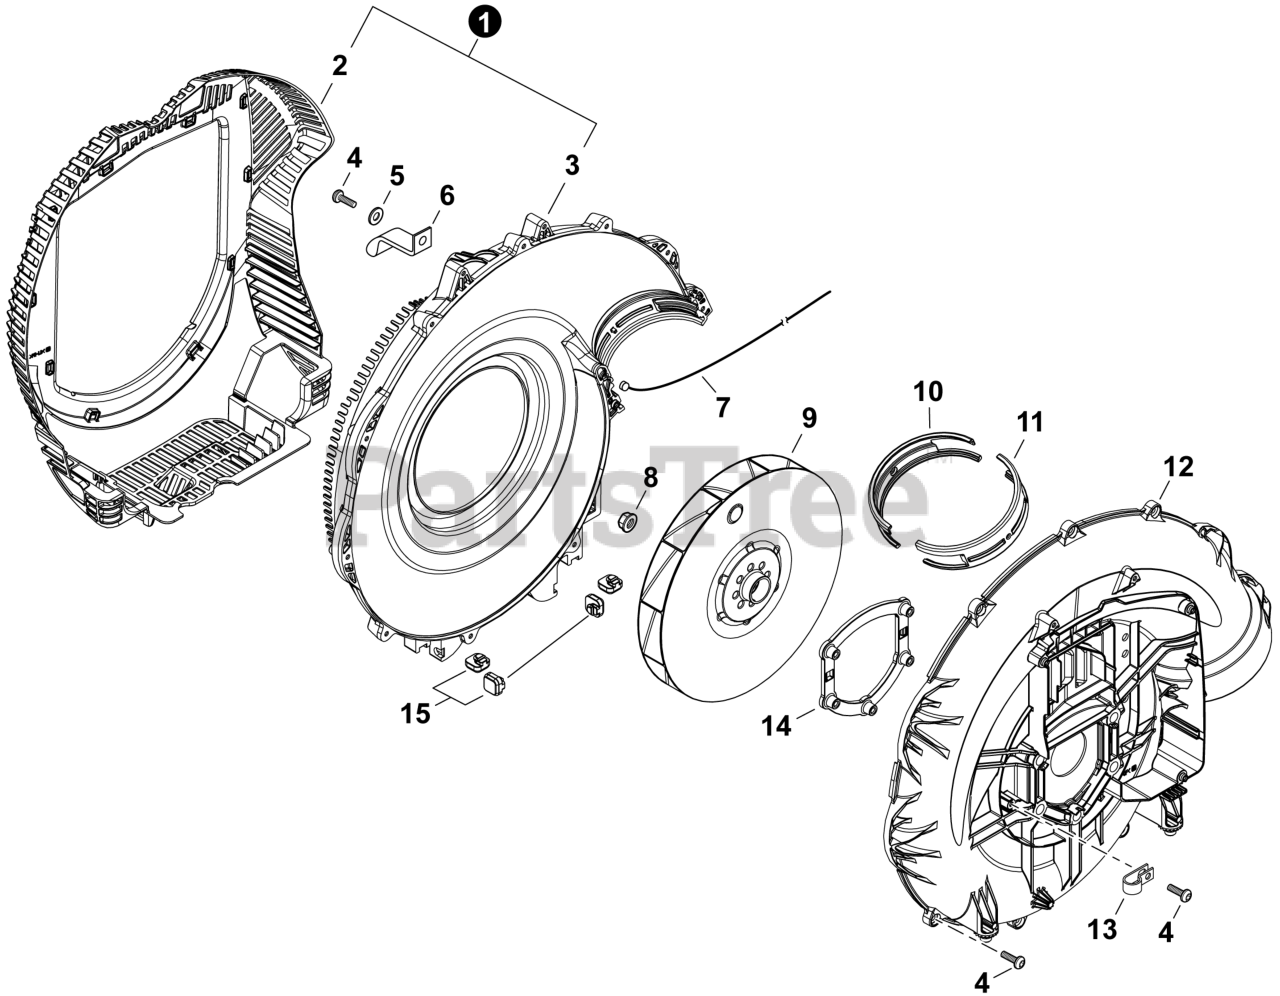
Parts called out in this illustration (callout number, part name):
1	FAN COVER/GUARD SET
2	GUARD, DEBRIS
3	COVER, FAN
4	BOLT, TORX 5x20
5	WASHER 5.5x16x0.8
6	STRAP, SAFETY
7	WIRE, ANTI-STATIC
8	NUT, FLANGE 10x1.25
9	FAN, BLOWER
12	CASE, FAN
13	CLIP
14	PLATE, ENGINE
15	CUSHION
